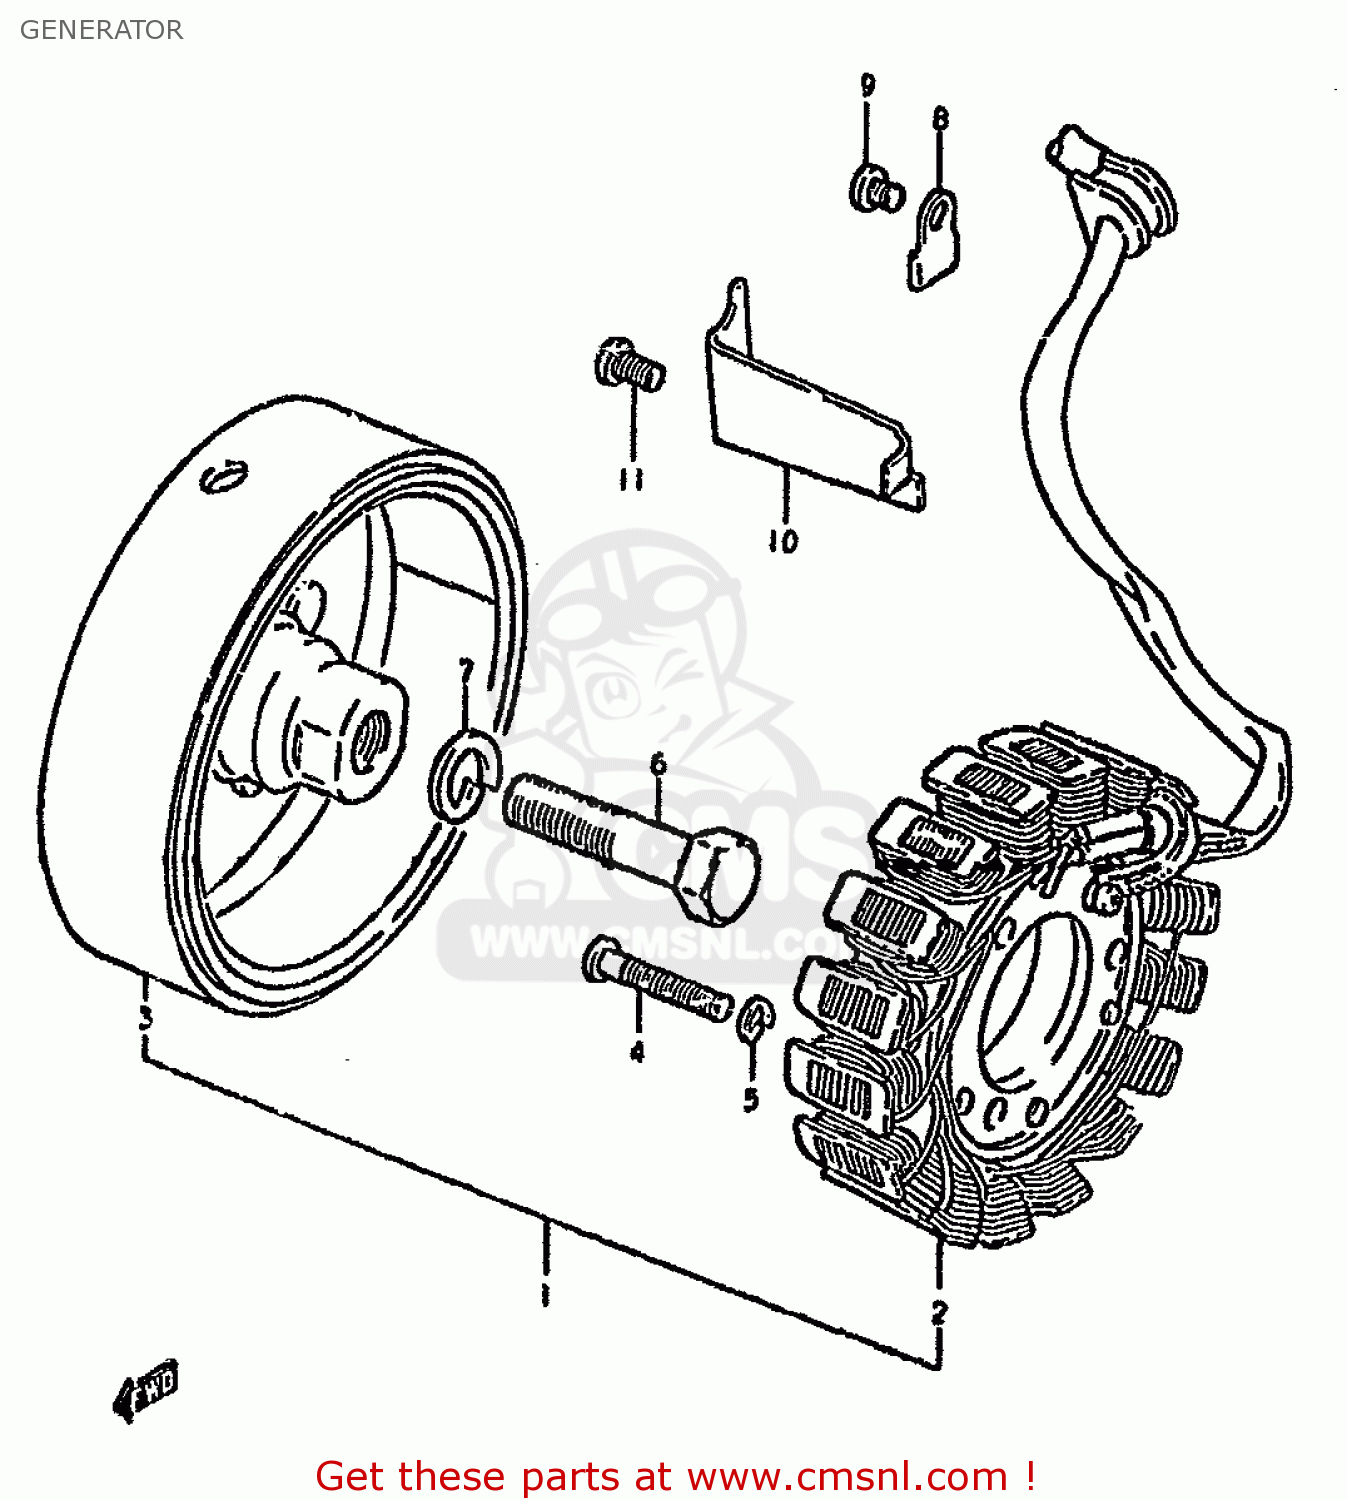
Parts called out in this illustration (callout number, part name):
1	GENERATOR ASSEMBLY
2	STATOR ASSEMBLY
3	ROTOR ASSEMBLY
4	SCREW
5	LOCK WASHER
6	BOLT 12X45
7	WASHER,LOCK 12
8	CLAMP,GENERATOR LEAD WIRE
9	SCREW
10	CLAMP,GENERATOR LEAD WIRE
11	SCREW
